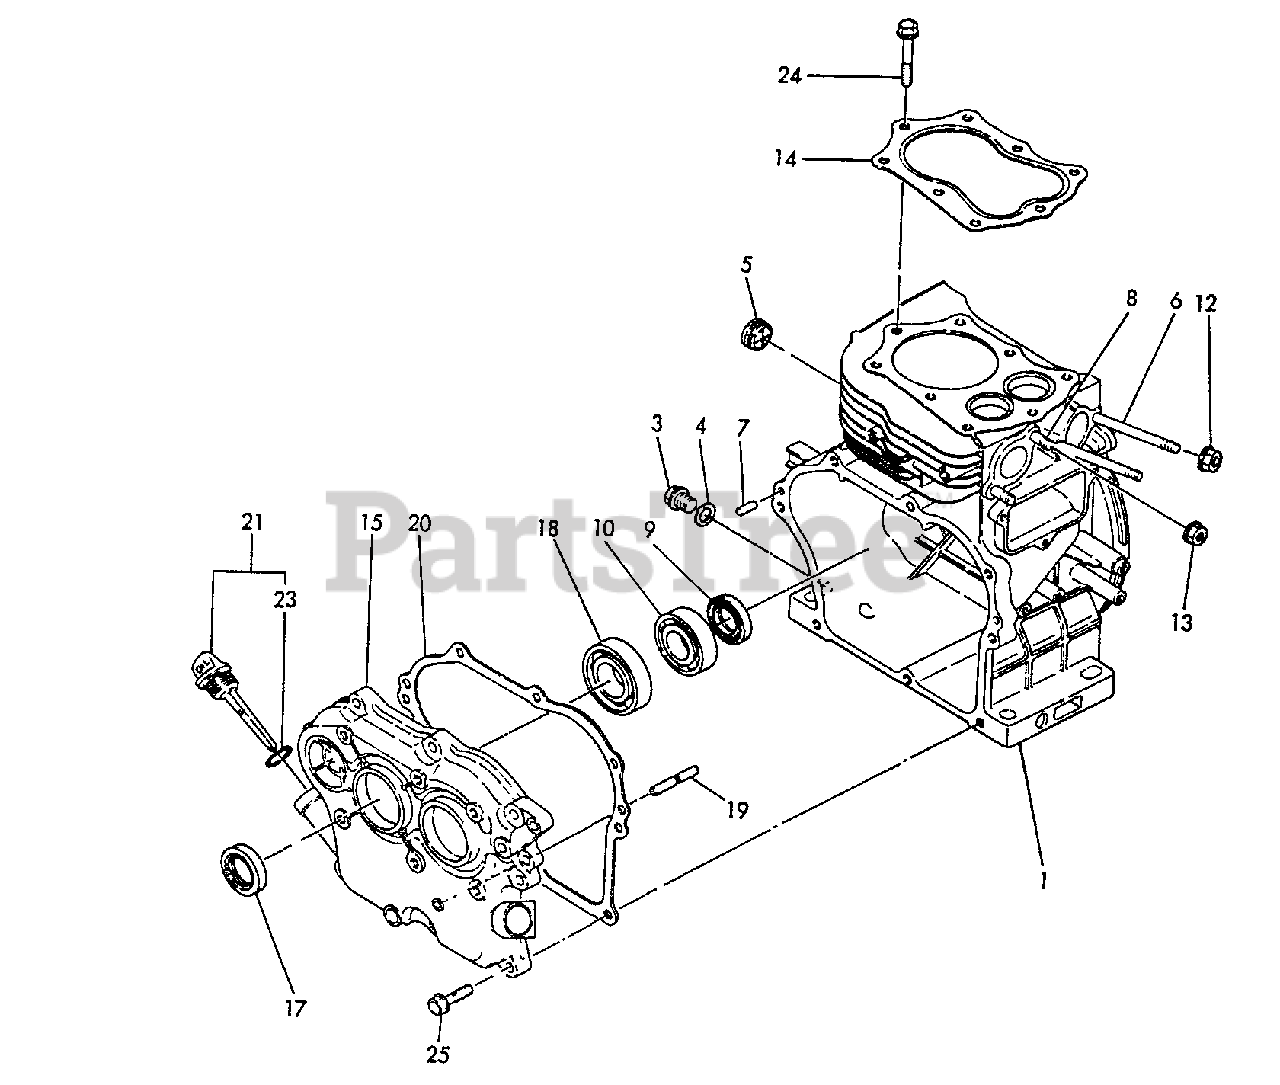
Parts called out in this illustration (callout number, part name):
1	CYLINDER BLOCK SET
3	PLUG, DRAIN
4	GASKET
5	PLUG
6	BOLT - 6X90
7	PIN - 6X16
8	STUD - 8X18 -- PLATED
9	SEAL, OIL
10	BEARING, BALL - 6205C3
12	NUT - 6 -- FLANGE
13	NUT - 8
14	GASKET, CYLINDER
15	SIDE COVER ASSY
17	SEAL, OIL
18	BEARING, BALL - 6206C4
19	SHAFT, GOVERNOR
20	GASKET, SIDE COVER
21	OIL FILLER CAP ASSY
23	O-RING - 18
24	BOLT - 8X50
25	BOLT - 8X30 -- PLATED
